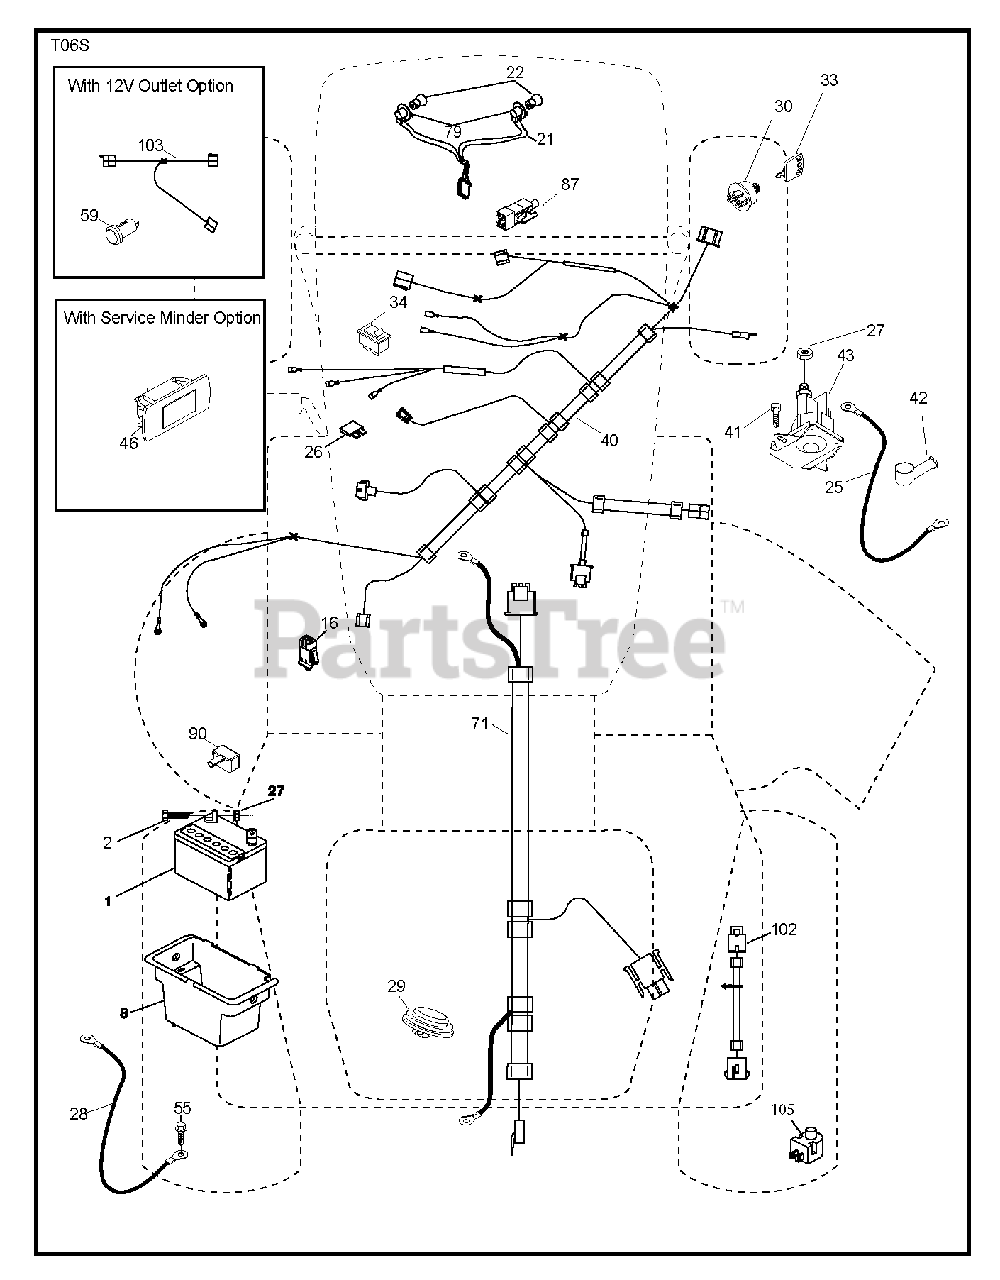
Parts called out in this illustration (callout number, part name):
2	BOLT LT
16	SWITCH INTERLOOK PUSH-IN
22	LIGHTBULB
25	CABLE STARTER
26	FUSE 20AMP
29	SWITCH.SEAT.DELTA.OPC.
30	IGNITION SWITCH
33	KEY/CHAIN.BLISTER.PACK.GEN.USA
34	SWITCH LT
43	SOLENOID.W/BRASS.PLUNG
79	BULB HOLDER ASM.
102	HARNESS PIGTAIL PCH TEX ROS
105	REVERSE SWITCH
